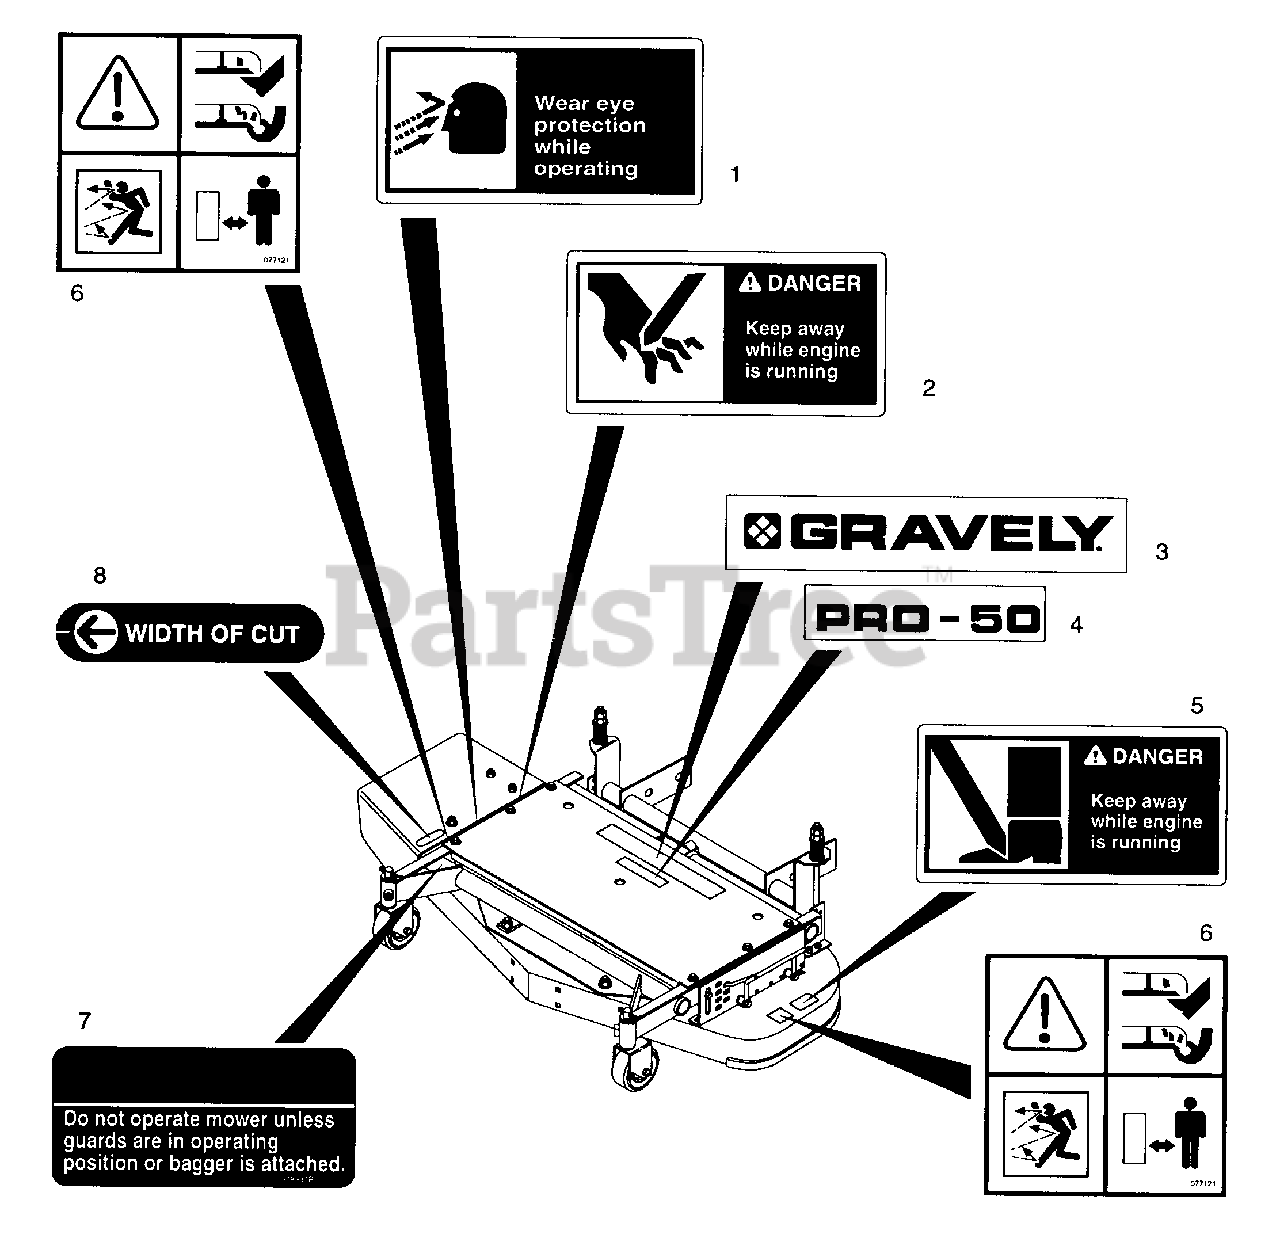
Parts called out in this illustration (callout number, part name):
1	Decal, Warning Eye
2	Decal, Danger Hand
3	Decal, Gravely
4	Decal, Pro-50
5	Decal, Danger Foot
6	Decal, Mower Pan Foreign (303)
7	Decal, Warning
8	Decal, Width of Cut
